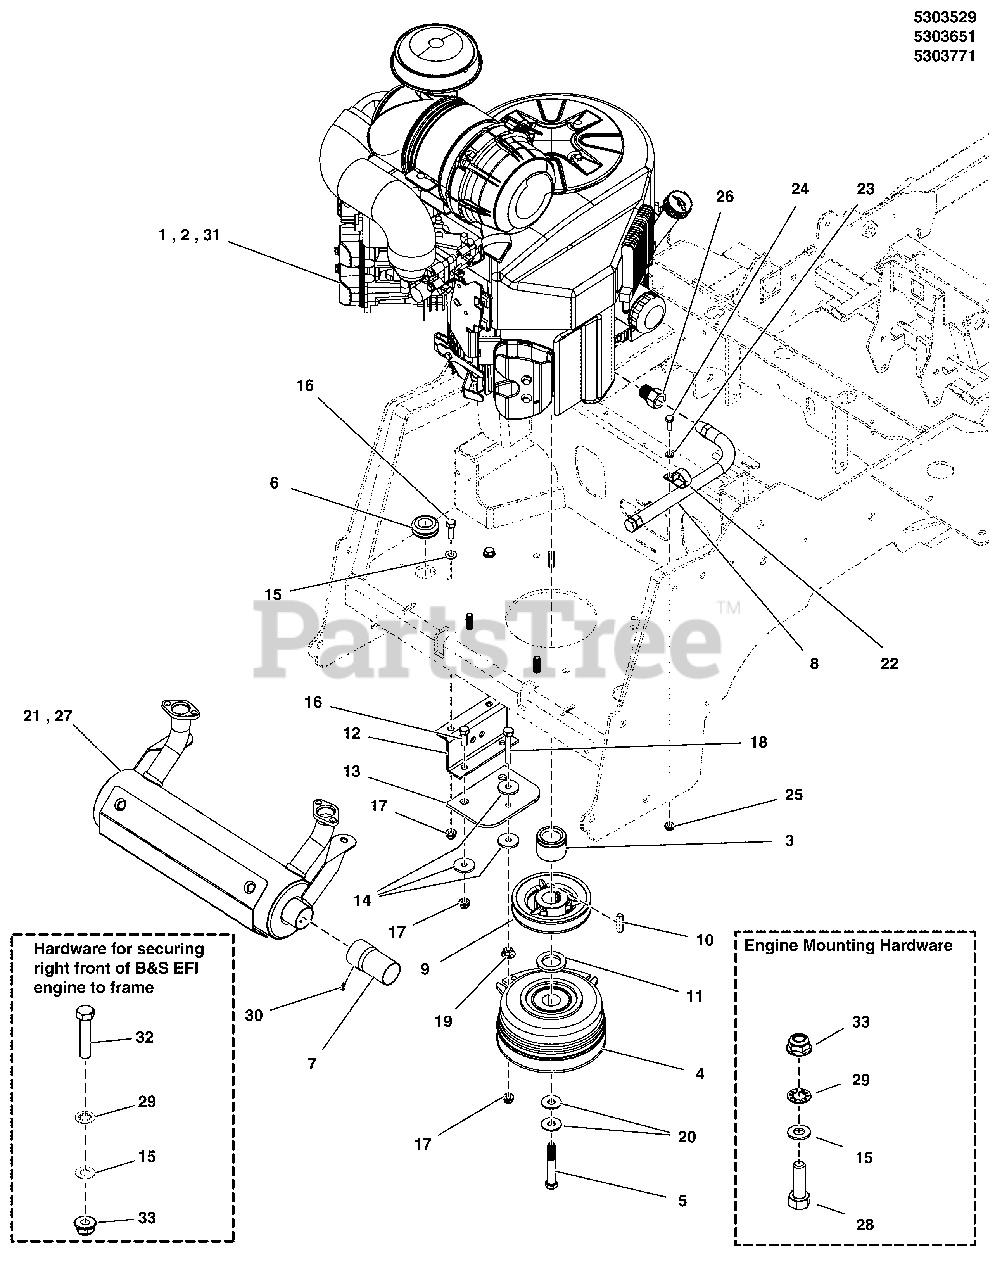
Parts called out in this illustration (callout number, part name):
1	ENGINE, BRIGGS & STRATTON, VANGUARD
2	ENGINE, B&S, 543777
3	SPACER, 1.13 X 1.75 X 1.35, CZ
4	CLUTCH, WARNER, 200 FT-LB, 1.13" X 6.323
5	BOLT, CRANKSHAFT, 7/16-20 X 3, GD8
6	GROMMET, 7/8"ID, 1/4" THICK STK
7	EXTENSION, TAILPIPE, 3", BLACK
8	HOSE, OIL DRAIN
9	PULLEY, 4.75 OD X 1-1/8 BORE, BC-48
10	KEY, 1/4 SQ. X 1-1/4
11	SPACER, 1.13 X 1.75 X .25
12	ANCHOR, CLUTCH, IS600-IS700 - BLK
13	PAD, Clutch Anchor
14	WASHER, CLUTCH ANCHOR, 5/16
15	WASHER, 5/16
16	CAPSCREW, Hex Head, 5/16-18 X 1
17	NUT, Ny Lock Flange, 5/16-18
18	BOLT, 5/16-18 X 2-1/4, GD 5, TFL, ZN
19	NUT, 5/16-18 HEX SERRATED FLANGE (LARGE)
20	BELLEVILLE, WASHER, 1.1875 X .442 X .089
21	Muffler
22	CLAMP, VINYL INSULATED, 1.00
23	WASHER, 1/4, Flat, GR5 Zinc/Clear
24	CAPSCREW, Hex Head, 1/4-20 x 3/4 (stiffener to top of cover)
25	NUT, Serrated Flange, 1/4-20
26	METRIC ADAPTER, M14-1.5" TO 3/8 NPTF
27	MUFFLER, RIGHT OUTLET ASSY
28	BOLT, 5/16-24 X 1-3/4, GD8, PHOS
29	WASHER, 5/16" Internal Tooth Lock
30	SCREW,SELF-TAP,#8-32 X 3/8, WASH HEX, CZ
31	ENGINE, 28HP BRIGGS VANGUARD, EFI
32	BOLT-HEX, 5/16-24 X 1-1/2", GD8, PHOS
33	NUT, 5/16-24, TOP LOCK FLANGE, GD8 PHOS
